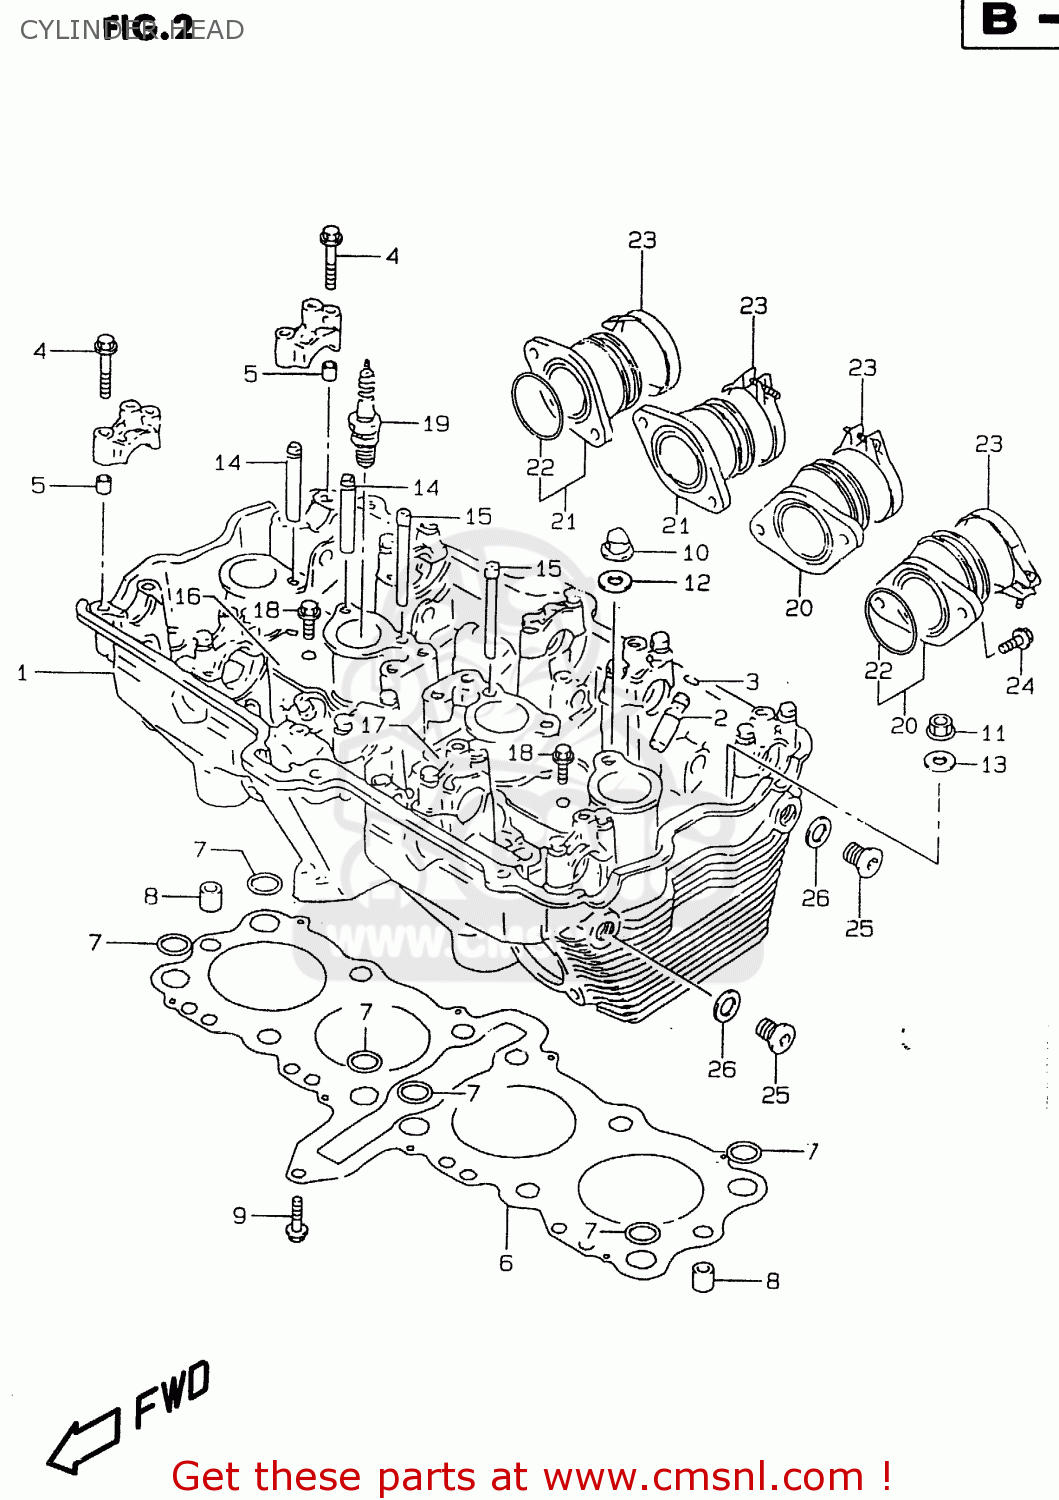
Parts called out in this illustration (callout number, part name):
1	HEAD ASSEMBLY,CYLINDER
2	GUIDE,VALVE
3	RING,SNAP
4	BOLT(6X39)
5	PIN(6.2X8X11)
6	GASKET,CYLINDER HEAD (NAS)
7	O RING(D:2.6,ID:12.1)
8	PIN
9	BOLT
10	NUT
11	NUT
12	GASKET(10.2X20X2).3 (NAS)
13	WASHER (10.5X22X2.3)
14	PIPE,OIL NO.1
15	PIPE,OIL NO.3
16	PLATE,OIL PIPE,R
17	PLATE,OIL PIPE,L
18	BOLT
19	PLUG,SPARK(CR9EK)
20	PIPE ASSY,INTAKE NO.1
21	PIPE ASSY,INTAKE NO.3
22	O RING(D:2.4,ID:39.7)
23	CLAMP
24	BOLT MAGNETO S
25	PLUG
26	GASKET(13.8X18.8X4.8) (NAS)
